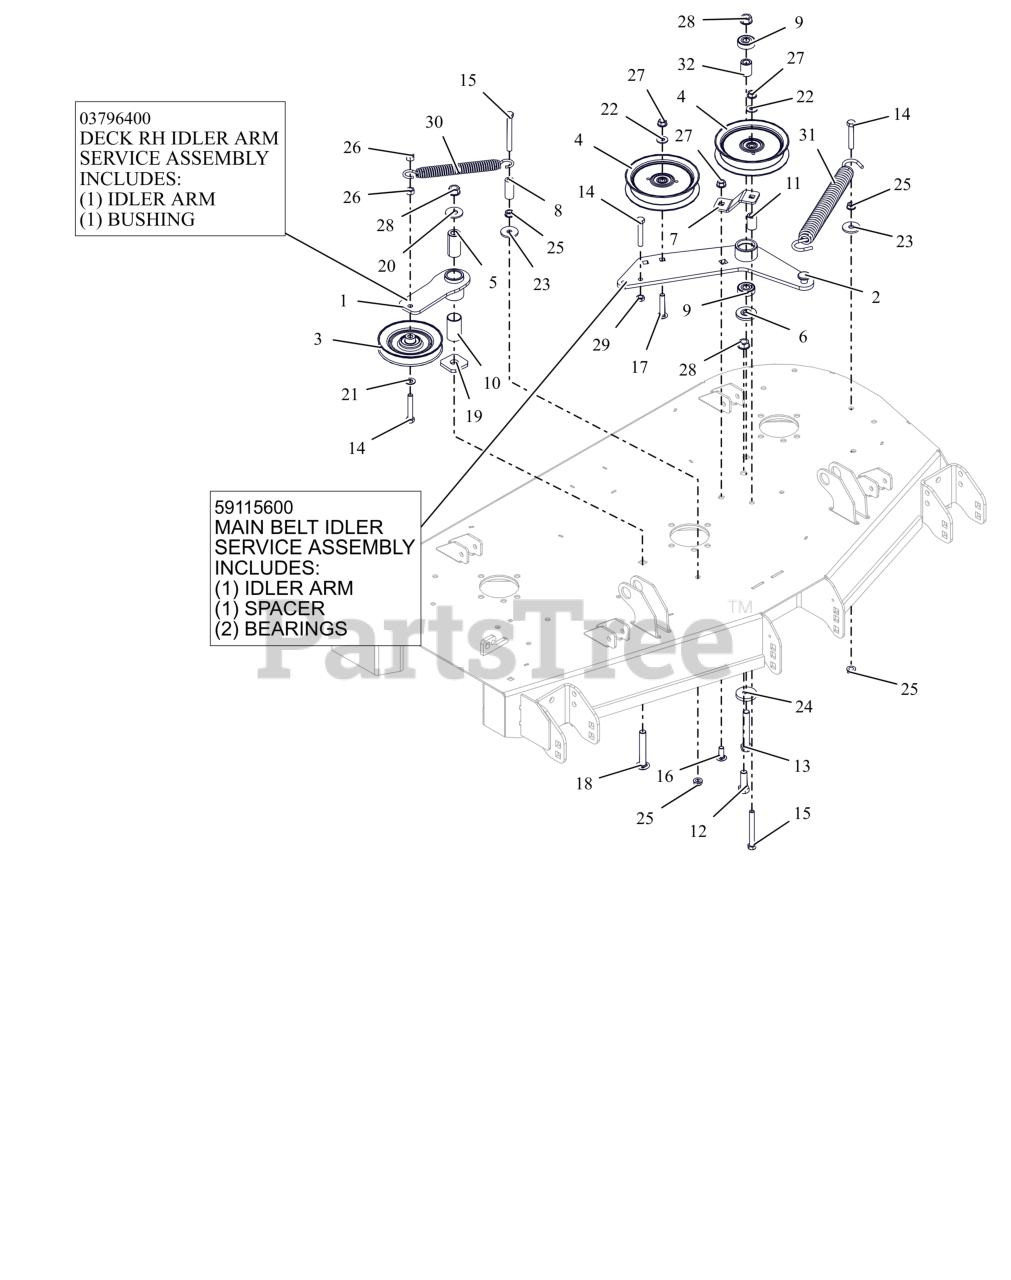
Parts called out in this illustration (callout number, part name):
1	WMT, IDLER ARM - BLACK
1	ASM, IDLER ARM (DECK)
2	WLDMT, DECK PTO IDLR ARM
2	ASSEMBLY, MAIN BELT IDLER
3	IDLER, V-5.00"
4	IDLER, FLAT 5.00"
5	BSHG, SPCR .502X.997X2.03 PM
6	SPACER, IDLER ARM
7	PTO FIXED IDLER MTG BRKT -RED
8	HOSE, .38 X 1.65
9	BRG-BALL .500X1.38X.437
10	BSHG, 1.00X1.125X1.937
11	BUSHING, SLV .380X.750X1.190
12	BLT,HEX .50-13X1.50 G5 ZCC
13	BLT,HEX .50-13X3.25 G5 ZCC
14	BLT,HEX .38-16X2.25 G5 ZCC
15	BLT, HEX .38-16X3.25 G5 ZCC
16	BLT,RHSSN .38-16X1.00 G5 ZCC
17	BLT,RHSSN.375-16X2.00 G5 ZCC
18	BTL,RHSSN .500-13 X 3.25 G5 ZCC
19	WSHR-FLT .640X1.75X.250
20	WSHR,FLT .563X1.375X.109 ZCC
21	WSHR,FLT .406X.812X.065 ZCC
22	WSHR,FLT .375X.875X.083 ZCC
23	WSHR,FLT .406X1.375X.135 ZCC
24	WSHR-FL-STL 0.557X1.625X0.25 ZCC
25	NUT, SPNLK-FLG .38-16 G5 ZCC
26	NUT-LK-CTR .38-16 ZC120
27	NUT-LK-CTR-FLG .375-16 GF ZCC
28	NUT-LK-CTR-FLG .500-13 GG ZCC
29	NUT-JAM .375-16 G2 ZCC
30	SPRING, EXTENSION
31	SPRING, EXTENSION
32	SPACER .510 X .75 X 1.1485
